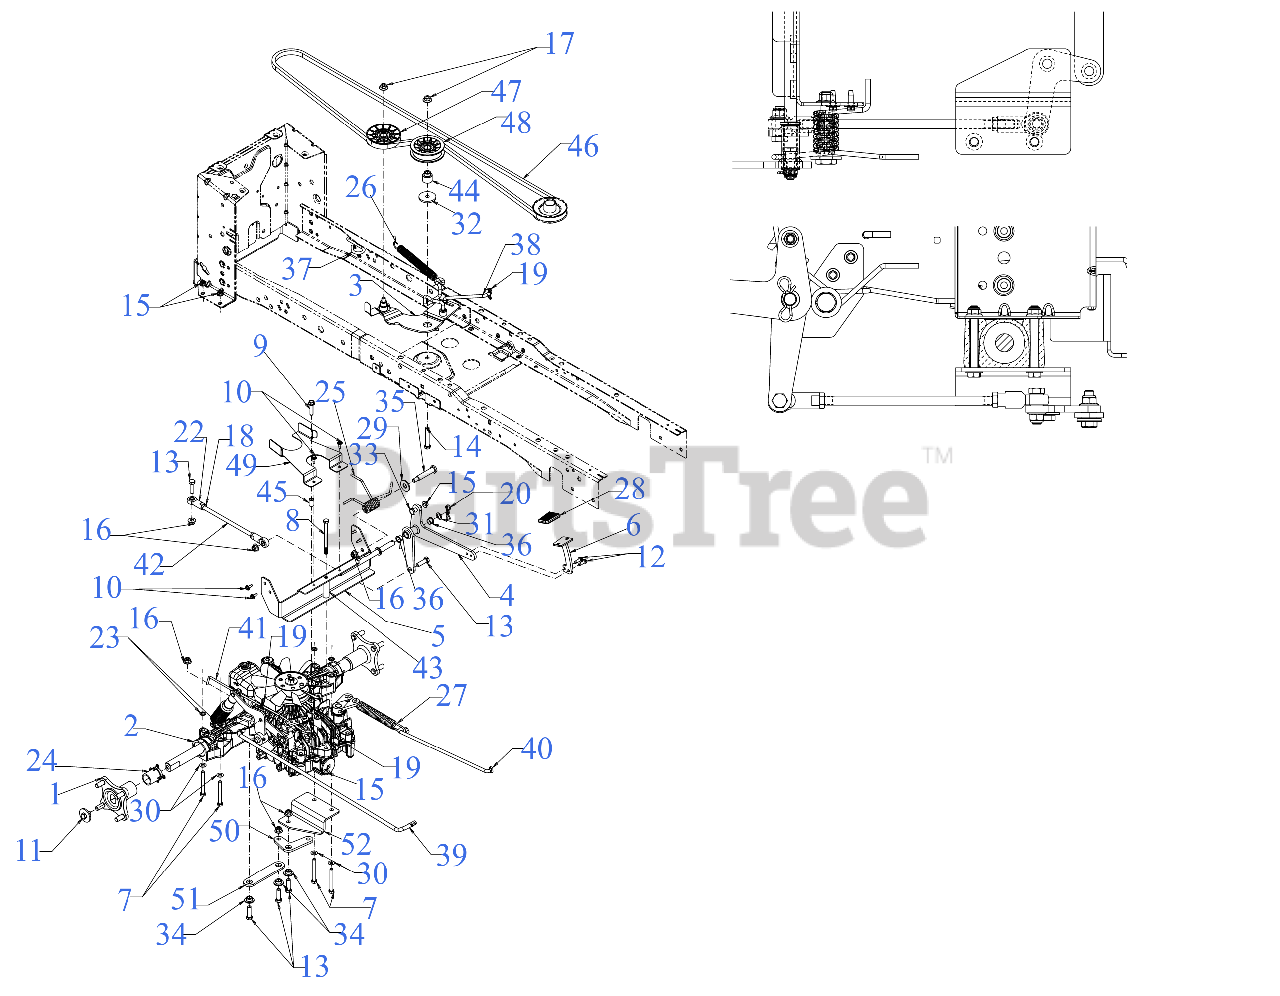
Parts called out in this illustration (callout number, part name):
1	WHEEL HUB ASSEMBLY
2	HYDRO TRANS ASSEMBLY
3	IDLER BRACKET ASSEMBLY
4	DIFF PEDAL PIVOT ASSEMBLY (PLATED)
6	DIFF LOCK PEDAL ASSEMBLY (PLATED)
7	HEX SCREW 5/16-18 x 2.75
8	HEX SCREW 5/16-18 x 4.00
9	HEX SCREW WASHER 5/16-18 x 1.5
10	SCREW M6-1 x .625
11	SCREW 3/8-16 x .75 GR5.1
12	SCREW 1/4-20 x .750
13	SCREW 3/8-16 x 1.25 GR5
14	SCREW 3/8-16 x 2.25 GR5
15	FLANGE LOCK NUT 5/16-18
17	FLANGE LOCK NUT
18	HEX JAM NUT 3/8X24
19	BOW TIE COTTER PIN 1/4-5/16
20	BOW TIE COTTER PIN
22	ROD END 3/8 ID
24	AXLE SLEEVE 1.02 ID x 1.60 LG
25	DIFF PEDAL TORSION SPRING
26	EXTENSION SPRING .790 DIA x 8.41
27	EXTENSION SPRING 0.90 DIA x 8.14
28	DIFF LOCK PEDAL PAD
29	FLAT WASHER
30	FLAT WASHER
31	THRUST WASHER
32	SHOULDER SPACER
33	SHOULDER SCREW
34	SHOULDER SPACER
35	SHOULDER SCREW .50 x 2.23 3/8-16
36	NYLINER BEARING
37	DECK SPRING HOOK
38	IDLER BRACKET ROD
39	HYDRO CONTROL ROD (PLATED)
40	BRAKE CONTROL ROD (PLATED)
41	HYDRO DISENGAGE ROD (TUFF TORQ)
42	ROD .375 OD x 8.75 LG (PLATED)
44	SHOULDER SPACER
45	SLEEVE .33X.50X.75 LG
46	V-BELT A SEC x 90.00
47	V-IDLER PULLEY 3.56 OD
48	FLAT IDLER PULLEY 3.00 OD
50	PIVOT BELLCRANK (PLATED)
51	BELLCRANK LINK (PLATED)
52	BELLCRANK MOUNTING BRACKET (PLATED)
